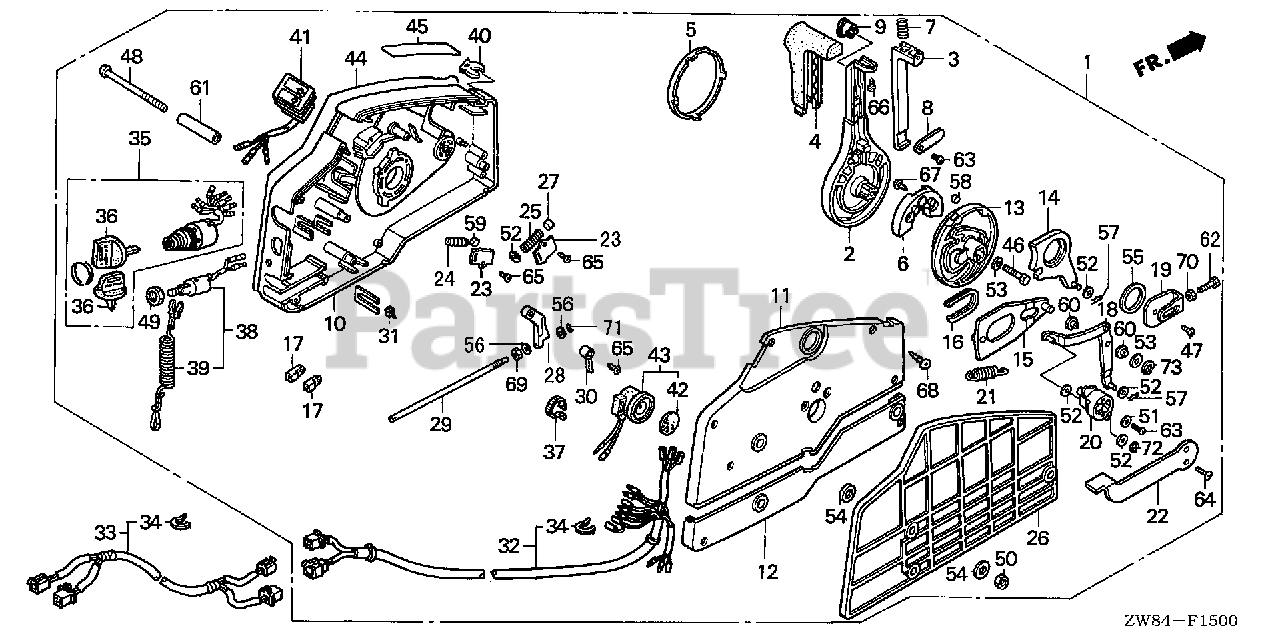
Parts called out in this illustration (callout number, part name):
1	BOX ASSY., REMOTE CONTROL
2	HANDLE, REMOTE CONTROL
3	LEVER, HANDLE LOCK
4	GRIP, REMOTE CONTROL HANDLE
5	CAP, HANDLE
6	BLOCK, NEUTRAL LOCK
7	SPRING, REMOTE CONTROL HANDLE
8	PLATE, LEVER SETTING
9	COVER, GRIP
10	HOUSING, REMOTE CONTROL BOX (A)
11	HOUSING, REMOTE CONTROL BOX (B)
12	HOUSING, REMOTE CONTROL BOX (C)
13	WHEEL, CONTROL
14	ARM, SHIFT LINK
15	PLATE, SLIDING
16	COLLAR, SLIDING PLATE
17	PIVOT, SHIFT
18	ARM, LINK JOINT
19	BRACKET, LINK JOINT
20	WHEEL, ACCELERATOR
21	SPRING, ACCELERATOR WHEEL
22	LEVER, IDLE
23	PLATE, SPRING SETTING
24	SPRING, SHIFT CLICK
25	SPRING, CHOKE RETURN
26	SPACER, REMOTE CONTROL BOX
27	SPACER, CLICK SPRING
28	BLOCK, THROTTLE FRICTION
29	BOLT, FRICTION
30	SPACER, NEUTRAL SWITCH
31	SPACER, CABLE CLAMP
32	CABLE ASSY. B, REMOTE CONTROL
33	CABLE ASSY., REMOTE CONTROL
34	TIE, CABLE
35	SWITCH ASSY., COMBINATION
36	KEY ASSY., COMBINATION SWITCH
38	SWITCH ASSY., EMERGENCY STOP
39	WIRE, EMERGENCY
40	CLIP, EMERGENCY LOCK
41	LAMP ASSY., INDICATOR
42	PLATE, TURN SIGNAL BUZZER
43	BUZZER, WARNING
44	PLATE, REMOTE CONTROL
45	MARK, FAST IDLE
46	BOLT, HEX. (8X35)
47	SCREW, PAN (6X10)
48	SCREW (6X95)
49	NUT, HEX. (16MM)
50	NUT, HEX. (6MM)
51	WASHER, PLAIN (5MM)
52	WASHER, PLAIN (6MM)
53	WASHER, PLAIN (8MM)
54	WASHER (6MM)
55	WASHER (28MM)
56	WASHER, PLAIN (4MM)
57	PIN, LOCK (6MM)
59	ROLLER, CLICK
60	COLLAR, LINK JOINT
61	COLLAR, DISTANCE (6X10X43.5)
62	BOLT, HEX. (5X16)
63	SCREW, PAN (5X10)
64	SCREW, OVAL (5X12)
65	SCREW, TAPPING (5X10)
66	SCREW, TAPPING (5X12)
67	SCREW, TAPPING (6X16)
68	SCREW, TAPPING (5X25)
69	NUT, HEX. (6MM)
70	NUT, HEX. (5MM)
71	E-RING (3MM)
72	E-RING (4MM)
73	E-RING (7MM)
